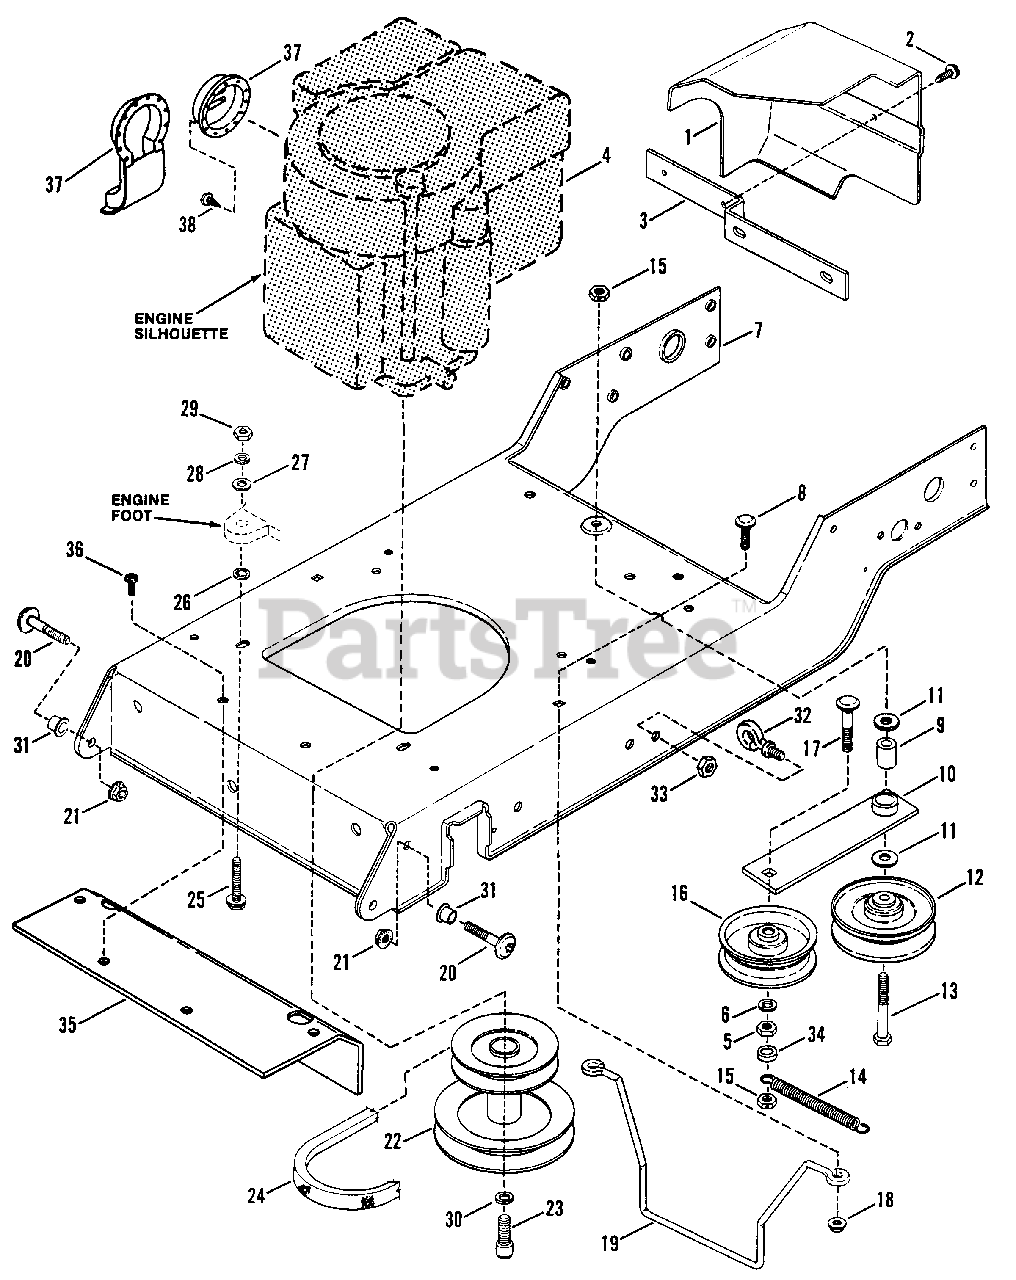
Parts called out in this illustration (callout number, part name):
1	HEAT SHIELD
2	SCREW, #10-24 x 1/2" H.W.S.T.
3	BRACKET, Heat Shield
5	NUT, 3/8-16 Hex
6	LOCKWASHER, 3/8 Split
7	BASE, Engine
8	BOLT, 5/16-18 x 3/4" Short Neck Carriage
9	BUSHING, Idler
10	ARM, Idler
11	WASHER, 3/8" Flat
12	PULLEY, Idler, 4" O.D.
13	BOLT, 3/8-16 x 2-1/4" Hex
14	SPRING, Idler Arm
15	LOCKNUT, 3/8-16 Hex, Center Lock
16	PULLEY, Idler, 3-3/4" O.D.
17	BOLT, 3/8-16 x 2-1/2" Short Neck Carriage
18	LOCKNUT, 5/16-18 Hex Flange
19	GUIDE, Belt
20	SCREW, Shoulder, 3/8-18 x 1-5/8"
21	LOCKNUT, 3/8-16 Hex Flange
22	PULLEY ASSEMBLY, Engine
23	CAPSCREW, 7/16-20 Hex Socket Head
24	V-Belt, Traction Drive, LT12D 33 & LT12D41
25	SCREW, 5/16-18 x 1-1/2" Hex Head Cap
26	RETAINER, Bolt
27	WASHER, 5/16 Flat
28	LOCKWASHER, 5/16" Split
29	NUT, 5/16-18 Hex
30	LOCKWASHER, 7/16" Split
31	BUSHING
32	EYE-BOLT
33	LOCKNUT, 5/16-18 Hex
34	SPACER
35	AXLE SUPPORT
36	SCREW, 5/16-18 x 5/8" Truss Hd. Torx
37	DEFLECTOR, Exhaust
38	SCREW, #8-18 x 3/8" Hex Hd. Tapered
